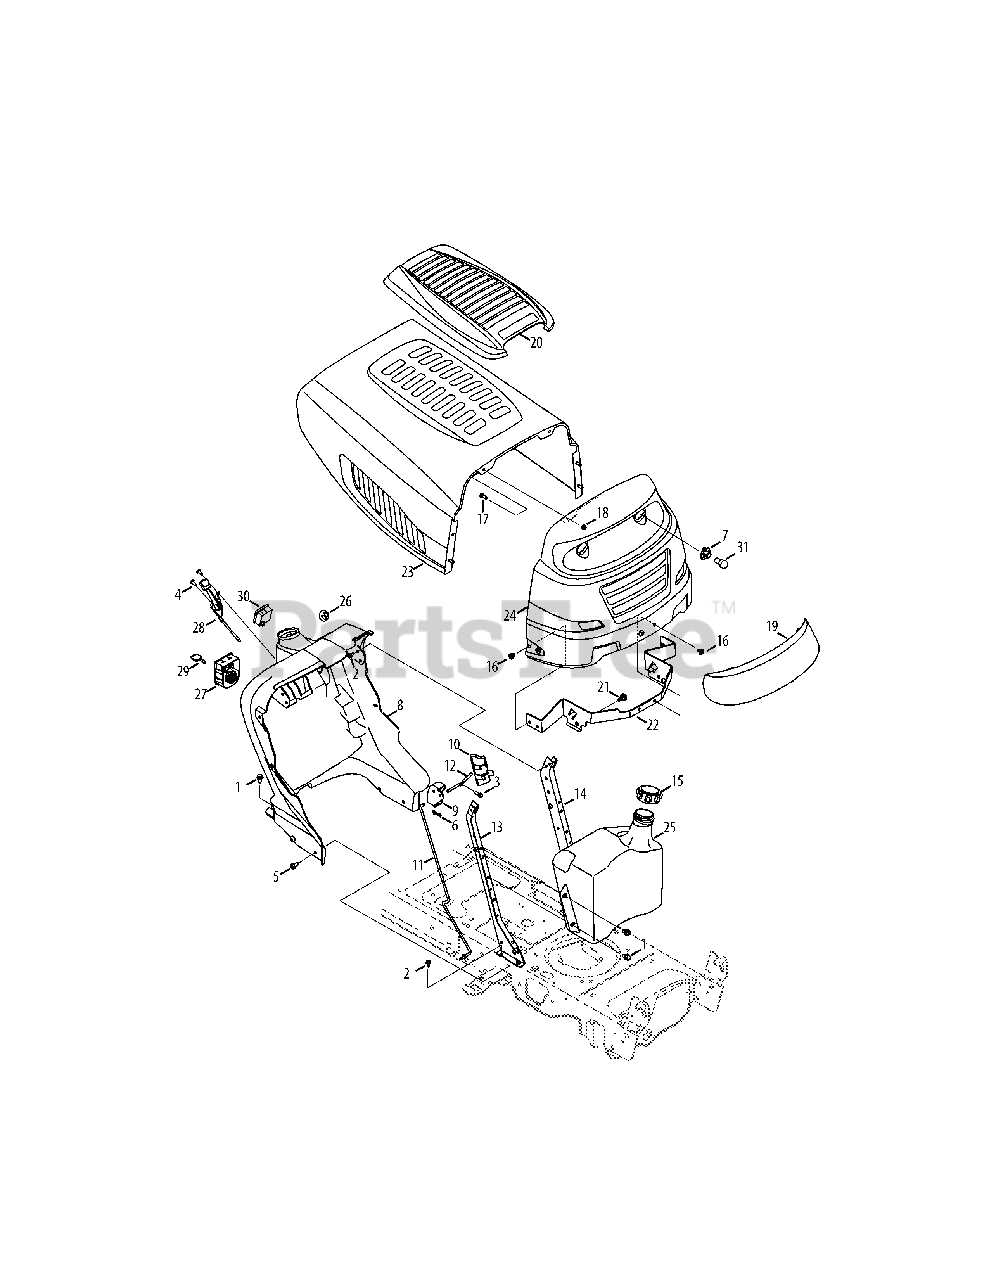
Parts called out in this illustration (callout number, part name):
1	Taptite Screw, 5/16-18:.750
2	Taptite Screw, 1/4-20:0.500
3	Hi-Lo Screw, 1/4-15:0.750
4	Screw, 1/4-14:0.625
5	Taptite Screw, 5/16-18:0.750
6	Bow Tie Cotter Pin
7	Lamp Socket
8	Dash Panel, No Sight Window
9	Dash Lever
10	Cruise Cover
11	Control Rod
12	Lever
13	RH Support Plate
14	LH Support Plate
15	Fuel Cap
16	Taptite Screw, 5/16-18:0.375
17	Hex Screw, 1/4-20:.620
18	Flangelock Nut, 1/4-20
19	Grill Lens
20	Hood Scoop
21	Shoulder Screw, .43X.29:5/16-18
22	Hood Pivot Bracket
24	Grill
25	Fuel Tank
26	Choke Plug
27	Key Switch Module
28	Throttle/Choke Control
30	Hour Meter
